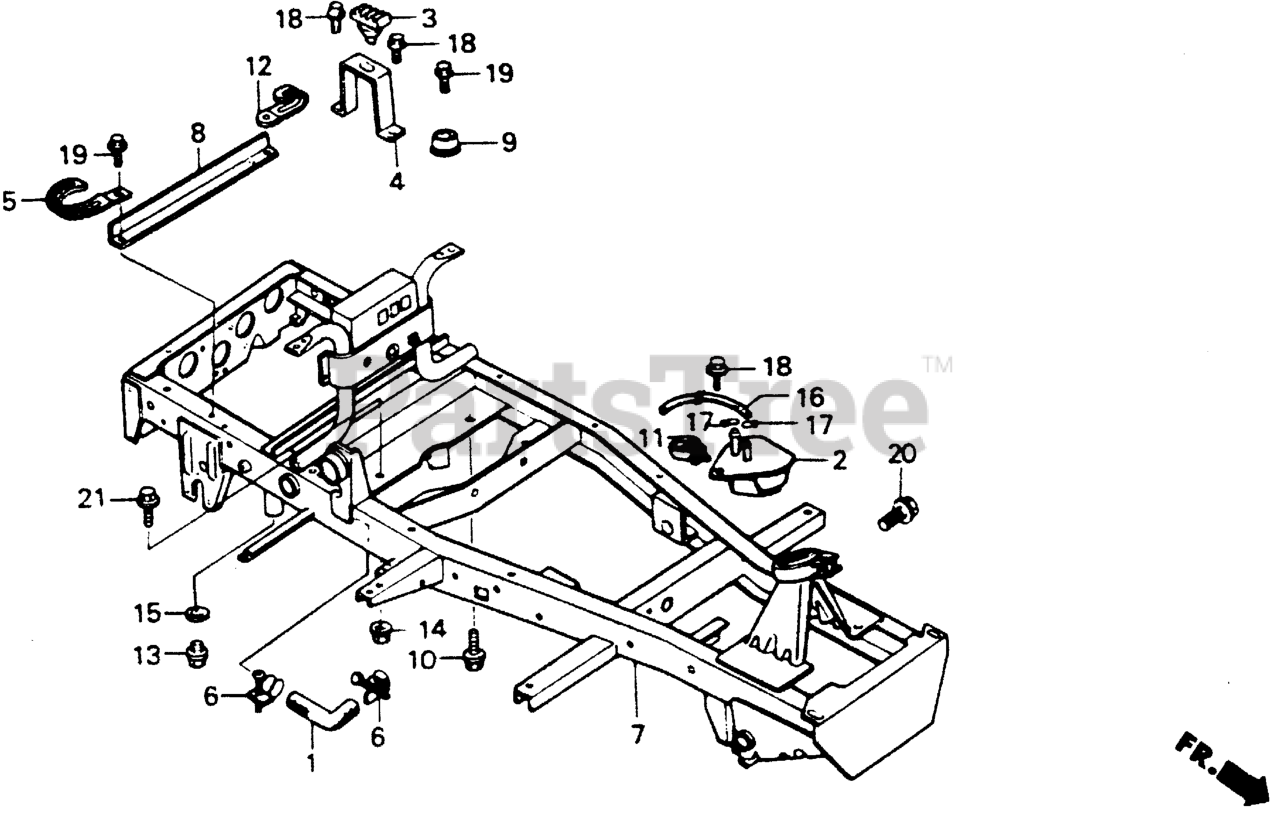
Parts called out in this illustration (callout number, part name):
1	TUBE, OIL DRAIN (NOT AVAILABLE)
2	TANK, FUEL CATCH (NOT AVAILABLE)
3	RUBBER, TANK CUSHION
4	STAY, TANK RUBBER
5	CLIP, WIRE HARNESS
6	CLAMP, MASTER CYLINDER OIL HOSE
7	FRAME
7	FRAME (NOT AVAILABLE)
8	HOLDER, BATTERY (B)
9	RUBBER (LOWER) Use from Frame SN 1008046.
10	BOLT, FLANGE (5/16"X22)
11	CLIP, WIRE HARNESS (25MM)
12	CLIP, WIRE HARNESS
13	BOLT, DRAIN PLUG (12MM)
14	NUT, FLANGE (8MM)
15	WASHER, DRAIN PLUG (12MM)
16	BULK HOSE, FUEL (4.5X3000) (Honda Code 5137104). (4.5X140)
17	CLIP, TUBE (B8)
18	BOLT, FLANGE (6X12) Use up to Engine SN 1543277.
19	BOLT, FLANGE (6X12) Use from Engine SN 2086984.
20	BOLT, FLANGE (8X25)
21	BOLT, FLANGE (8X35)
